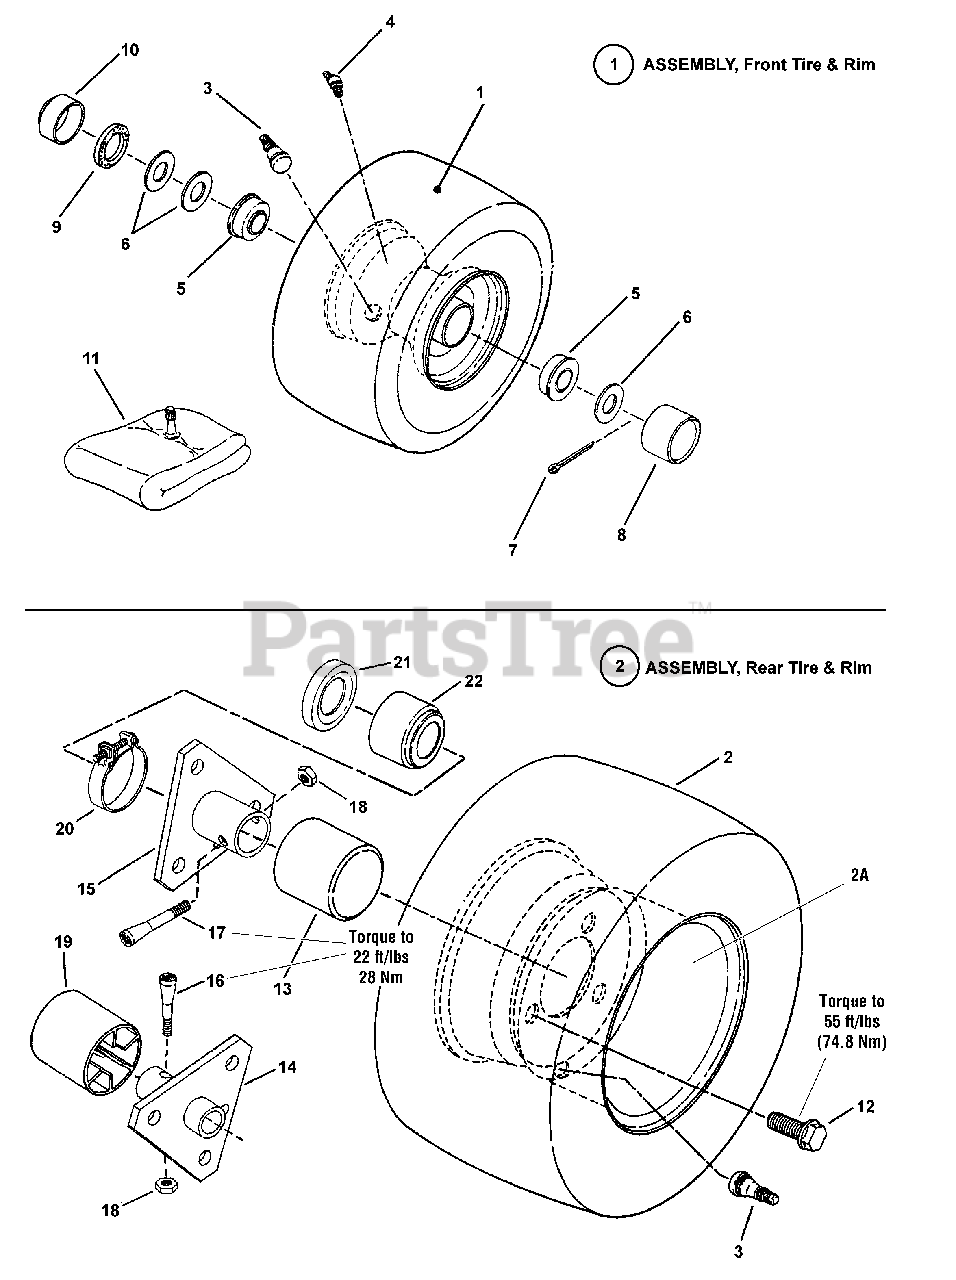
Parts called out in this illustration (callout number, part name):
01	ASSEMBLY, Front Wheel, 11x4.00 - 4
02	ASSEMBLY, Rear Wheel, K358, 15x6.50-8, Kenda
02A	RIM, 8X5.375 3 Hole, Extra Wide (For 16/7.50 x 8 Tire)
03	AIR VALVE STEM, Snap-In
04	LUBE FITTING, Straight (Press into 3/16" hole)
05	BEARING, Ball, Flanged (3/4 ID, 1-3/8 OD)
06	WASHER, .77 x 1.13 x .06, Flat
07	PIN, 5/32 x 1 Cotter
09	SEAL, Felt
10	CAP, Dust
11	TUBE, Inner (For 4.10/3.50 x 4 Tire)
12	BOLT, Hex Washer, 1/2-20 X .750
13	CAP, Hub, R.H., 1.35 ID x 2.25"
14	HUB, Rear Wheel, 3 Hole 3/4 ID, LH
15	HUB, Rear Wheel, 3 Hole 1.25 ID, RH
16	BOLT, 5/16-24 x 1-5/8 Tapered, Axle (Left Hand)
17	BOLT, 5/16-24 x 2 Tapered, Axle (Right Hand)
18	NUT, 5/16-24, Hex Crown Lock,GR C, Zinc/Clear
19	CAP, Hub, L.H., .975 ID x 2.25"
20	CLAMP, 2 ID
21	SEAL, 1.22 ID x 1.875 OD
22	CAP, Seal 1.0 ID x 1.67 OD
